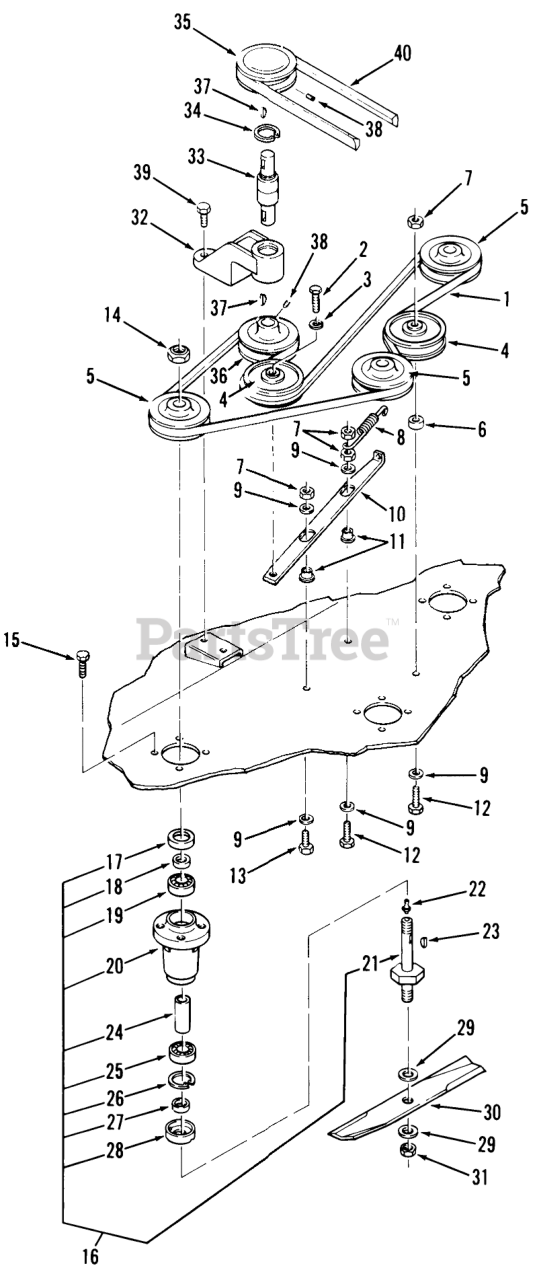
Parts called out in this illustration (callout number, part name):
1	V-BELT
2	BOLT HEX SPECIAL
3	LOCKWASHER
4	Idler Pulley
5	PULLEY-BLADE DRIVE
6	SPACER
7	Nut
8	SPRING-EXTENSION
9	WASHER
10	BAR-SLIDER
11	Bushing/Spacer
12	Bolt
13	Bolt
14	Nut
15	Bolt
16	Spindle Assembly
18	SPACER-SEAL
19	BEARING-BALL
20	HOUSING-SPINDLE
21	Spindle Shaft
22	Grease Fitting
23	Hi-Pro Key 3/16 x 5/8
24	SPACER
25	BEARING-BALL
26	Ring-Snap
27	SPACER-BLADE
28	CUP-SPINDLE
29	Washer
30	BLADE KIT
31	Nut
32	HOUSING DRIVE BRG R
33	BEARING-INT SHAFT
34	Snap Ring
35	PULLEY
36	Pulley
37	KEY-WOODRUFF
38	Set Screw
39	Bolt
40	Drive Belt
